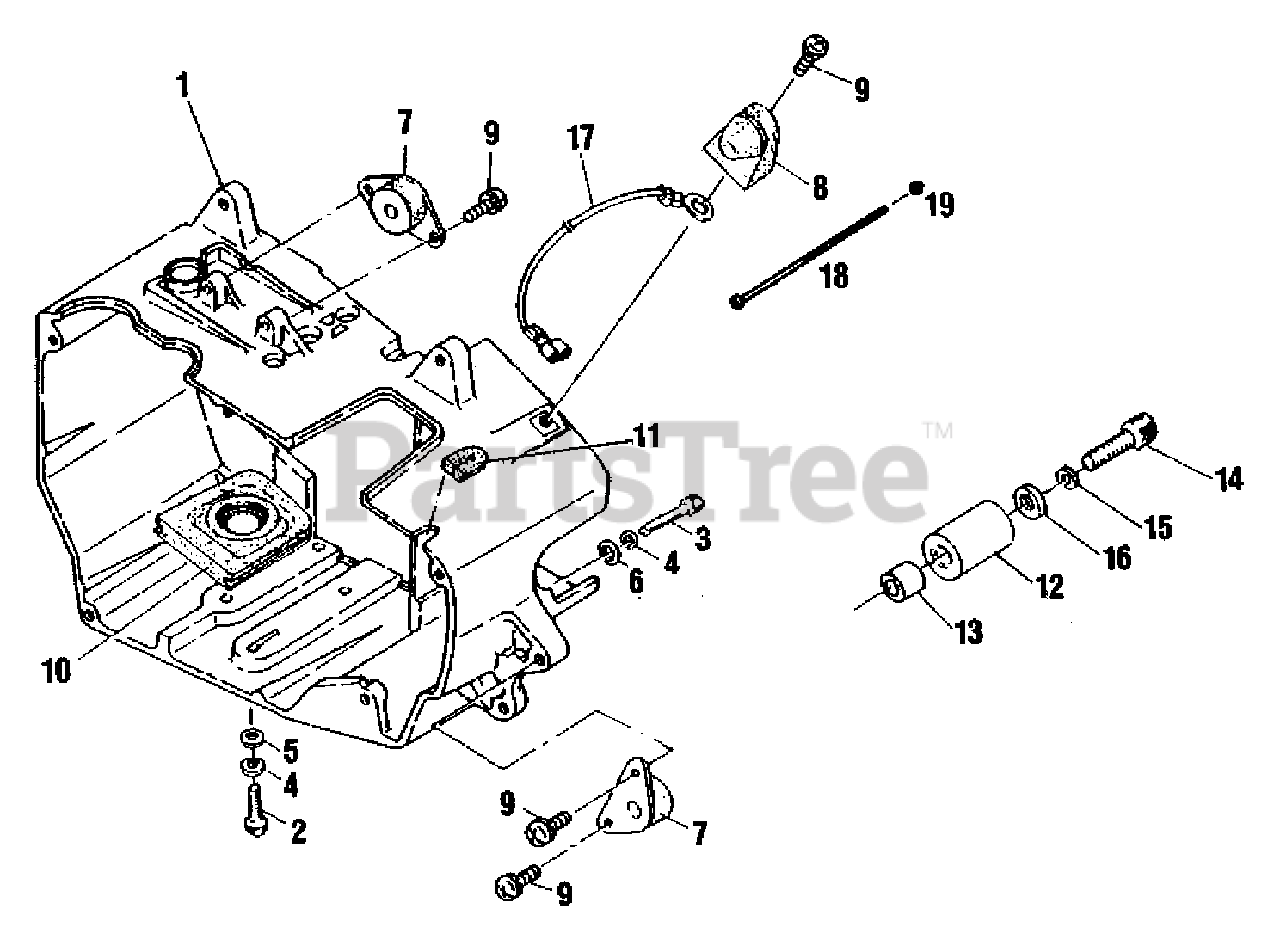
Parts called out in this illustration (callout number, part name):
1	CASE, ENGINE
2	BOLT M5×18
3	BOLT 5×25
4	WASHER, SPRING 5
5	WASHER, FLAT 5.5×10×0.8
6	WASHER
7	CUSHION 5
8	CUSHION 5
10	SEAL
11	GROMMET
12	CATCHER, CHAIN
13	BUSHING
14	BOLT 5×25
15	WASHER, SPRING 5
16	WASHER
17	GROUND CORD
18	SCREW
19	NUT
